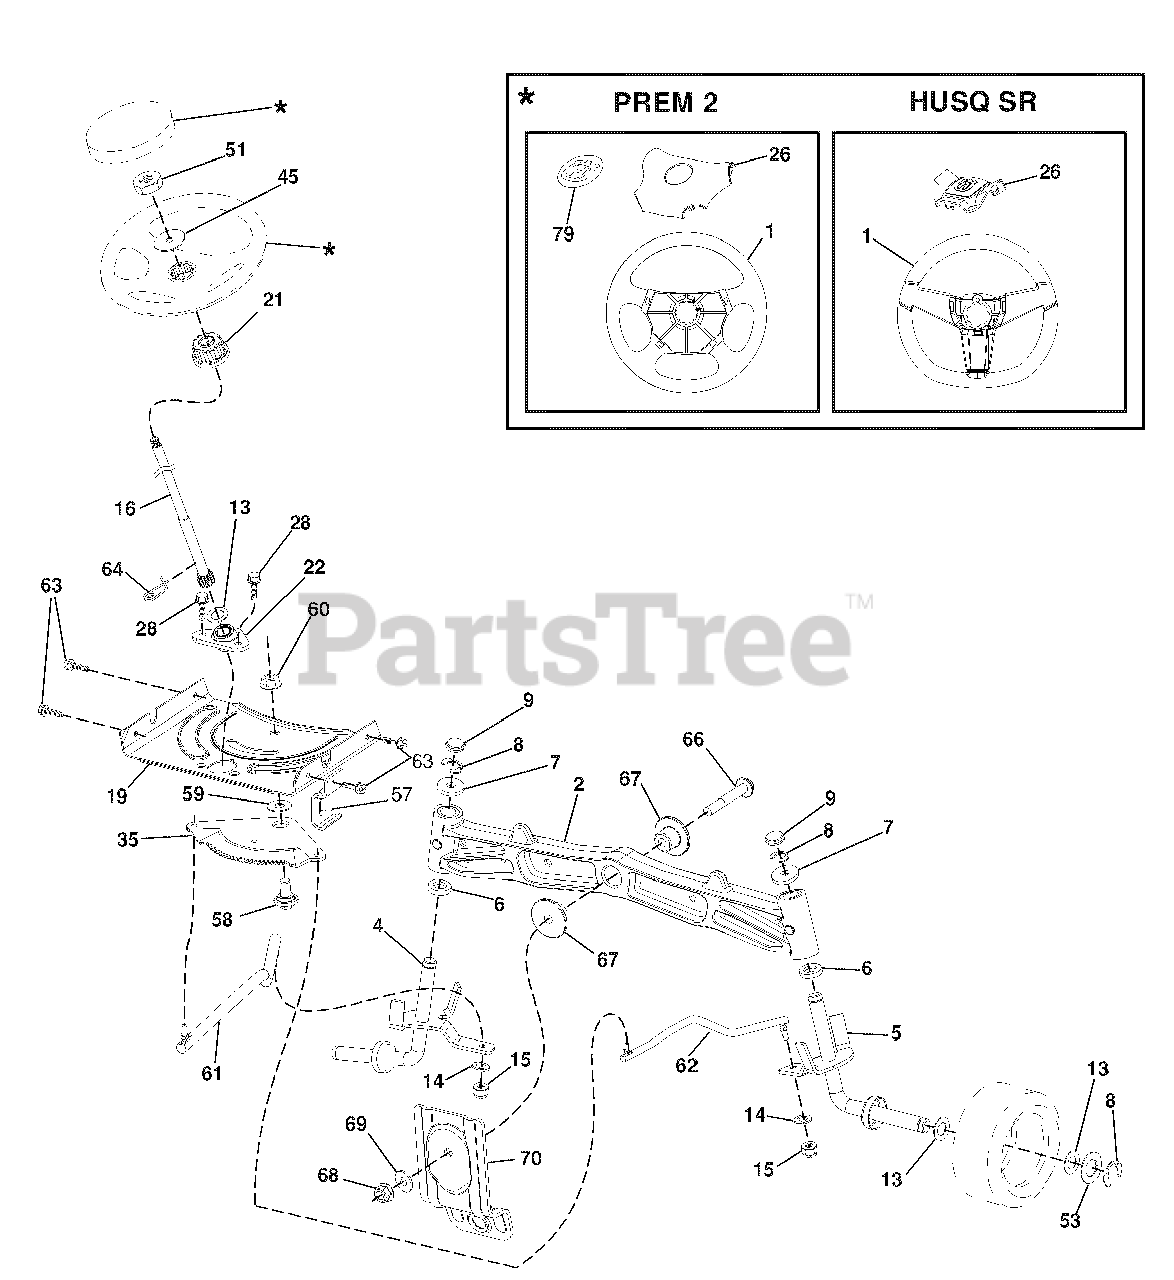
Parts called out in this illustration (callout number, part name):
1	Wheel, Steering
2	Axle Asm., Front
4	Spindle Asm., LH
5	Spindle Asm., RH
6	Bearing, Race Thrust Harden
7	Washer 25/32 x 1-5/8 x 16 Ga.
8	Ring, Klip #T5304-75
9	Cap, Spindle
13	Washer 25/32 x 1-1/4 x 16 Ga.
14	Washer, Lock Hvy Hlcl Spr 3/8
15	Nut, Crown Lock 3/8-24 unf
16	Shaft Steering
19	Plate Steering
21	Adapter, Wheel Steering
22	Bushing, Strg. Blk
26	Insert, Wheel Steering
28	Screw 3/8-16 x 3/4
35	Gear, Sector Plate
45	Washer 9/16 ID x 2-3/8 OD 12 Ga.
51	Nut Hex Jam Toplock 1/2-20 unf
53	Washer Hardened .793 x 1.637 x .060
57	Bracket Upstop
58	Bolt Shoulder Sector Pivot CFM
59	Washer Thrust Sector Steering
60	Nut Flange Lock 5/8-11
61	Draglink LH
62	Draglink, RH
63	Screw 5/16-18 x 3/4
64	Retainer Clip Spring Steering
66	Bolt Hex Fghd 7/16-14 x 3 Serr
67	Bushing PM Front Axle
68	Nut Lock Flange 7/16-14 Gr. 5
69	Washer 1.5 x .505 x .118
70	Bracket Deck Susp. Front
